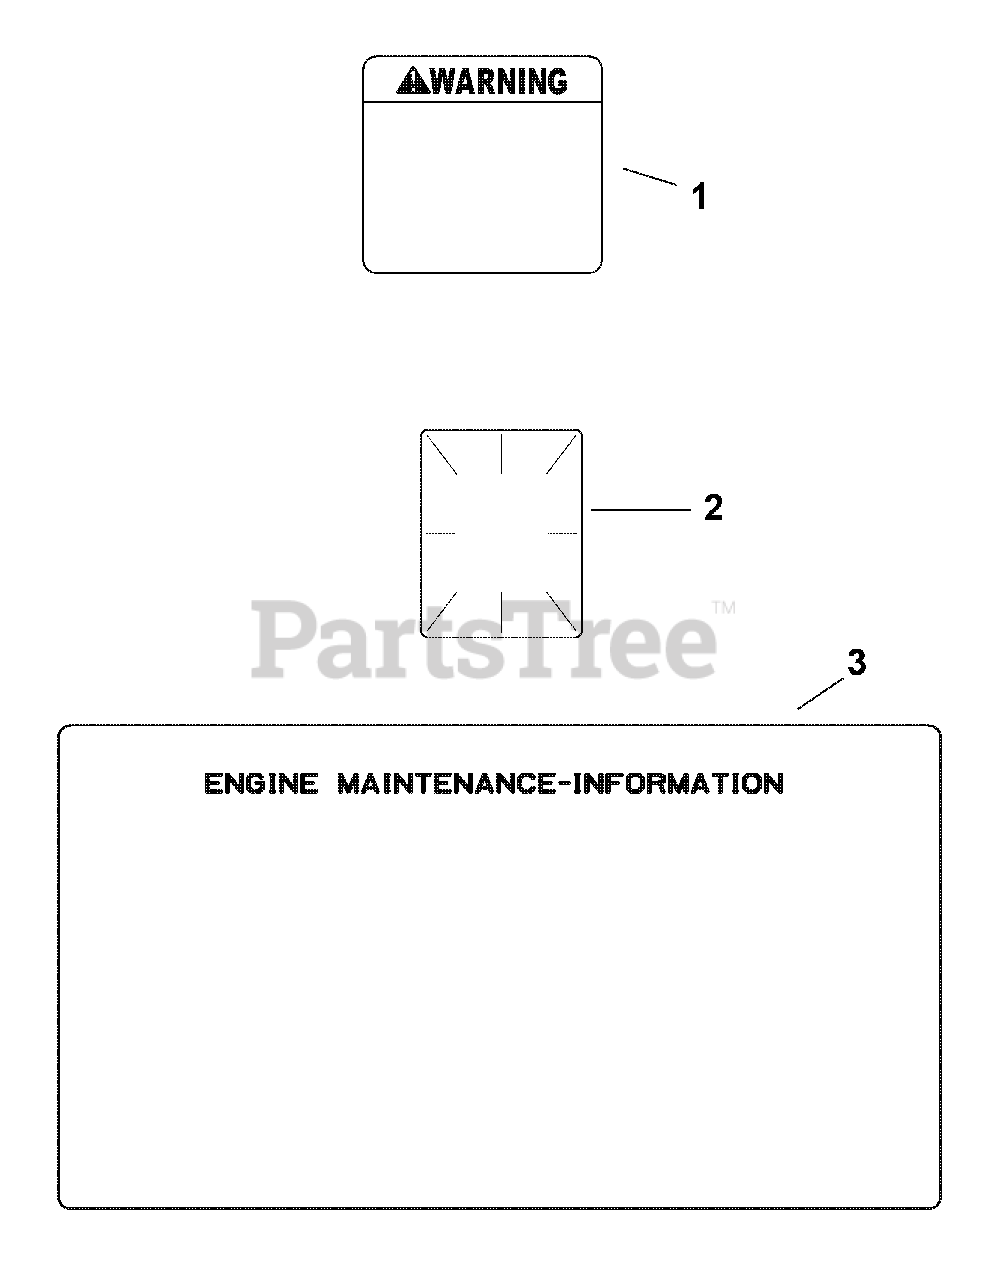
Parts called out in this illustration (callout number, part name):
1	Decal, Warning
2	Decal, Clear Laminate
3	Decal, Engine Maint.
